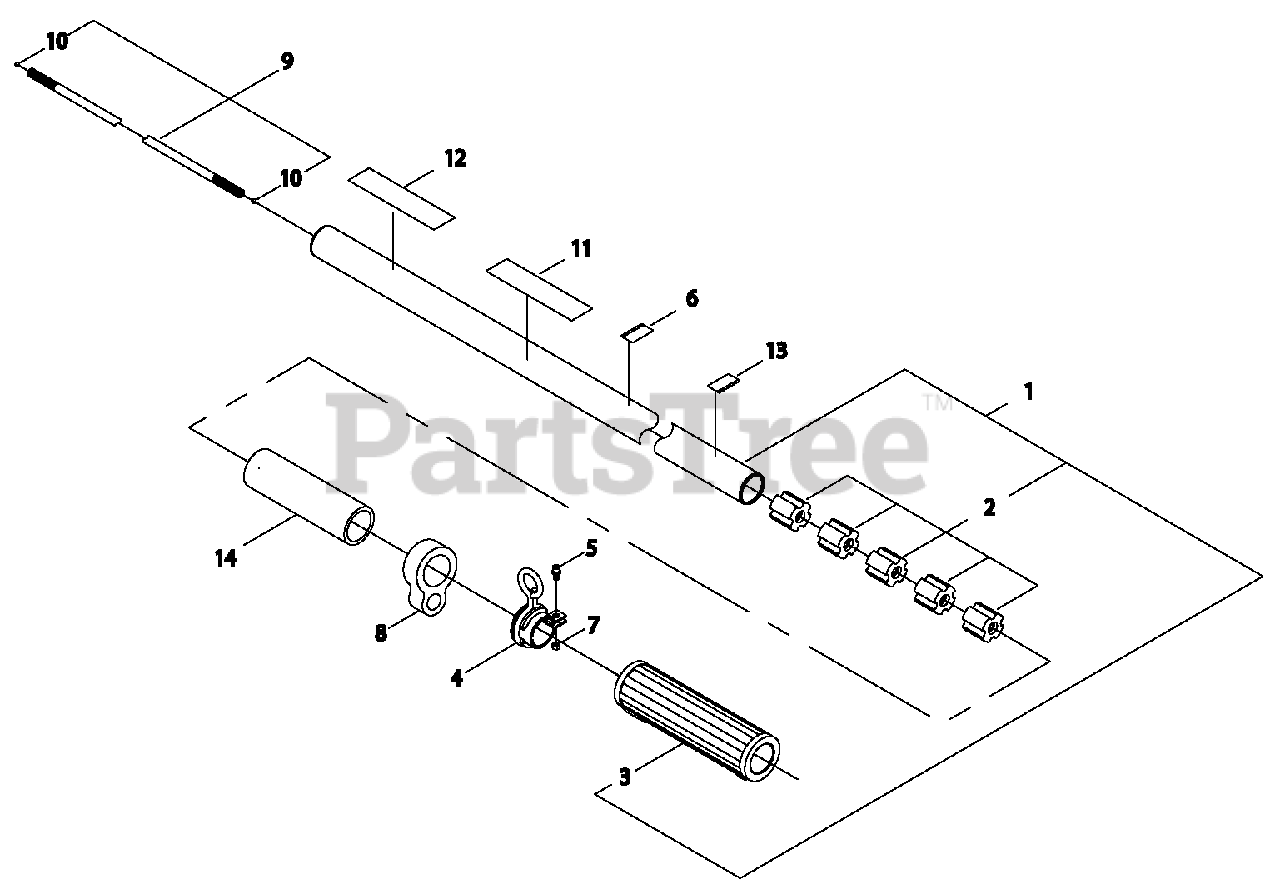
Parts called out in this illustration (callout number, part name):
1	MAIN PIPE ASSY
2	BUSHING
3	GRIP
4	HANGER
5	BOLT M5×12
6	LABEL, HANDLE
7	NUT M5
8	HOLDER, CABLE
9	DRIVESHAFT ASSY
10	STOPPER
11	LABEL, CAUTION (BLADE CAPABLE)
12	LABEL, SHINDAIWA PROFESSIONAL
13	LABEL - ALIGNMENT
14	PROTECTOR
